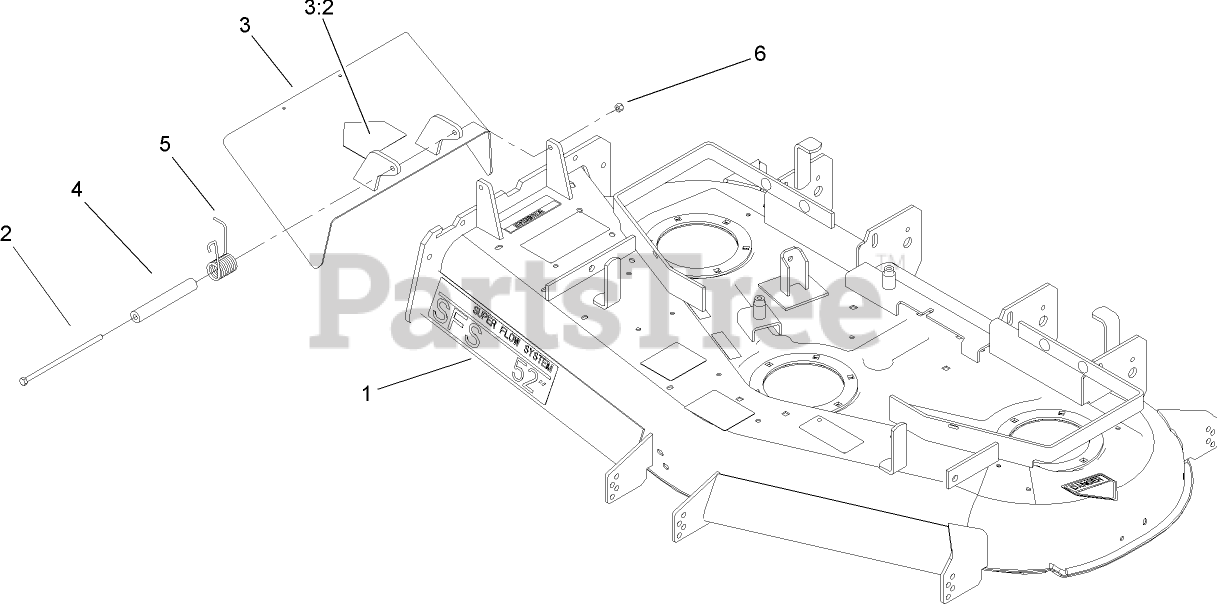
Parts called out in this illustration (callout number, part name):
1	DECK ASM
2	SCREW-HH
3	Deflector ASM
3:2	DECAL-DANGER
4	SPACER
5	SPRING-TORSION
6	NUT-LOCK, NI
